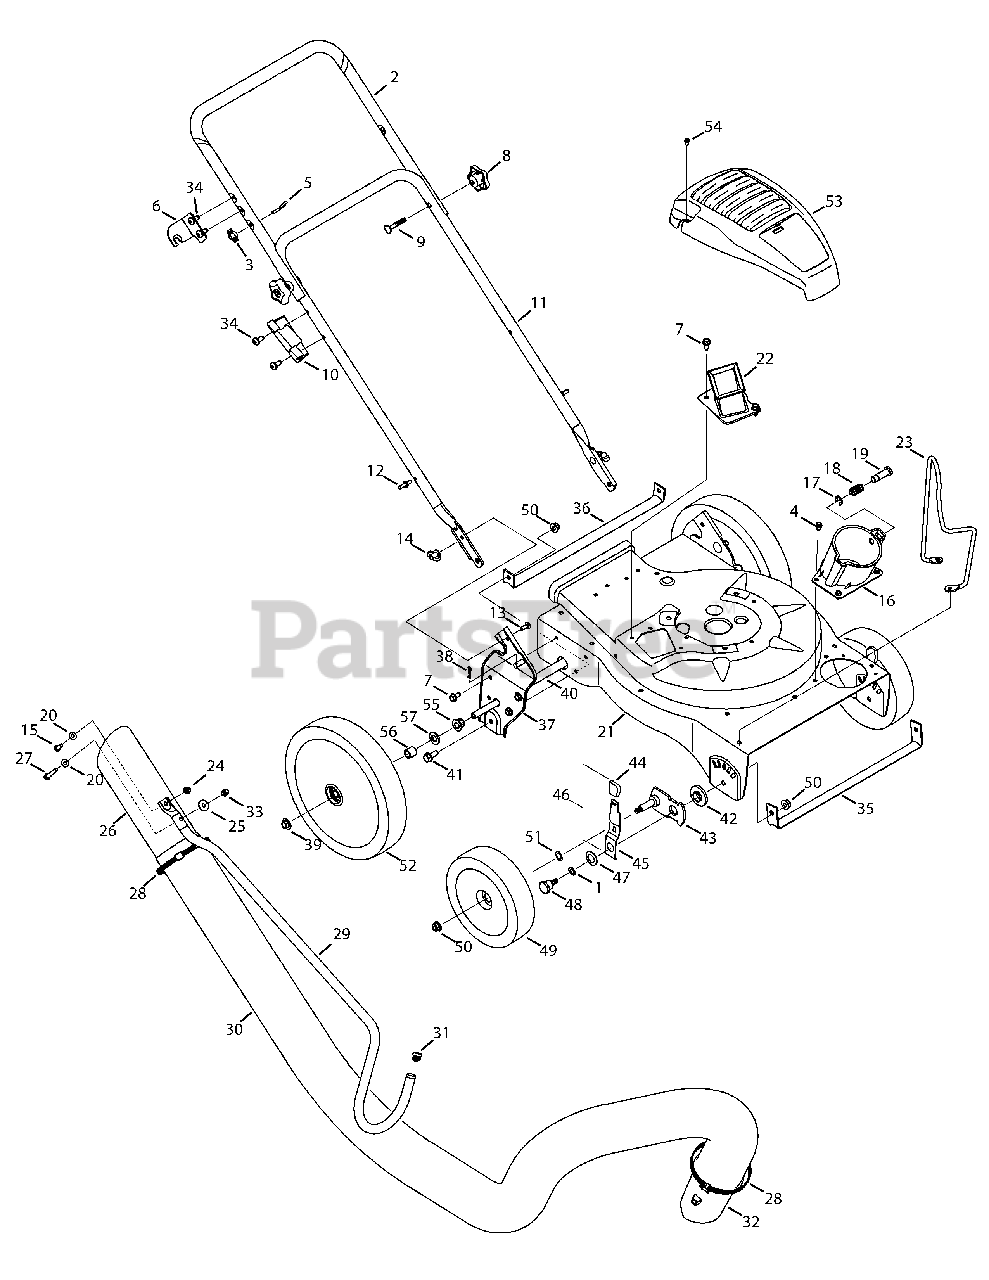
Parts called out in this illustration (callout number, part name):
1	Thrust Washer.375 ID x.70 OD
4	Screw, 1/4-20 x .500
6	Upper Handle Bracket
7	Hex Cap Screw 5/16-12 x.750
9	Carriage Bolt
10	Nozzle Handle Clip
13	Carriage Screw 1/4-20 x.75
14	Wing Nut 1/4-20
15	Hex Cap Screw 1/4-20 x.620
16	Hose Base Adapter Assembly
17	E Ring.500 Dia
18	Compression Spring
19	Clevis Pin
20	Flat Washer.271 ID x.630 OD
21	Upper Flail Housing
22	Chipper Chute Assembly
23	Hose Cradle
24	Flange Lock Nut, 1/4-20
26	Hose Nozzle
27	Hex Cap Screw 1/4-20 x 2.625
28	Adjustment Clamp
30	Vacuum Hose
31	Handle Plug
32	Hose Adapter
33	Cap Lock Nut, 1/4-20
34	TT Screw, 5/16-18 x .750
35	Front Wheel Support Brace
36	Rear Wheel Support Brace
37	Handle Bracket Ass’y RH
37	Handle Brkt Ass’y LH
38	Cotter Pin
41	HHflg, 3/8-16 x .875
42	Height Adjustment Bearing
43	Pivot Arm Assembly
44	Height Adjustment Knob
45	Spring Lever
46	Height Lever Assembly
47	Bell Washer.760 ID x.25 OD
48	Shoulder Screw,.750 x.500
49	Front Wheel
50	Flange Lock Nut, 3/8-16
51	Washer, Wave, .531 x .781 x .013
52	Rear Wheel
53	Engine Shroud
54	Screw, #12-16 x 1.00
55	Brg. Flg, Hex
57	Washer, Flat, .508ID x 1.00 OD
